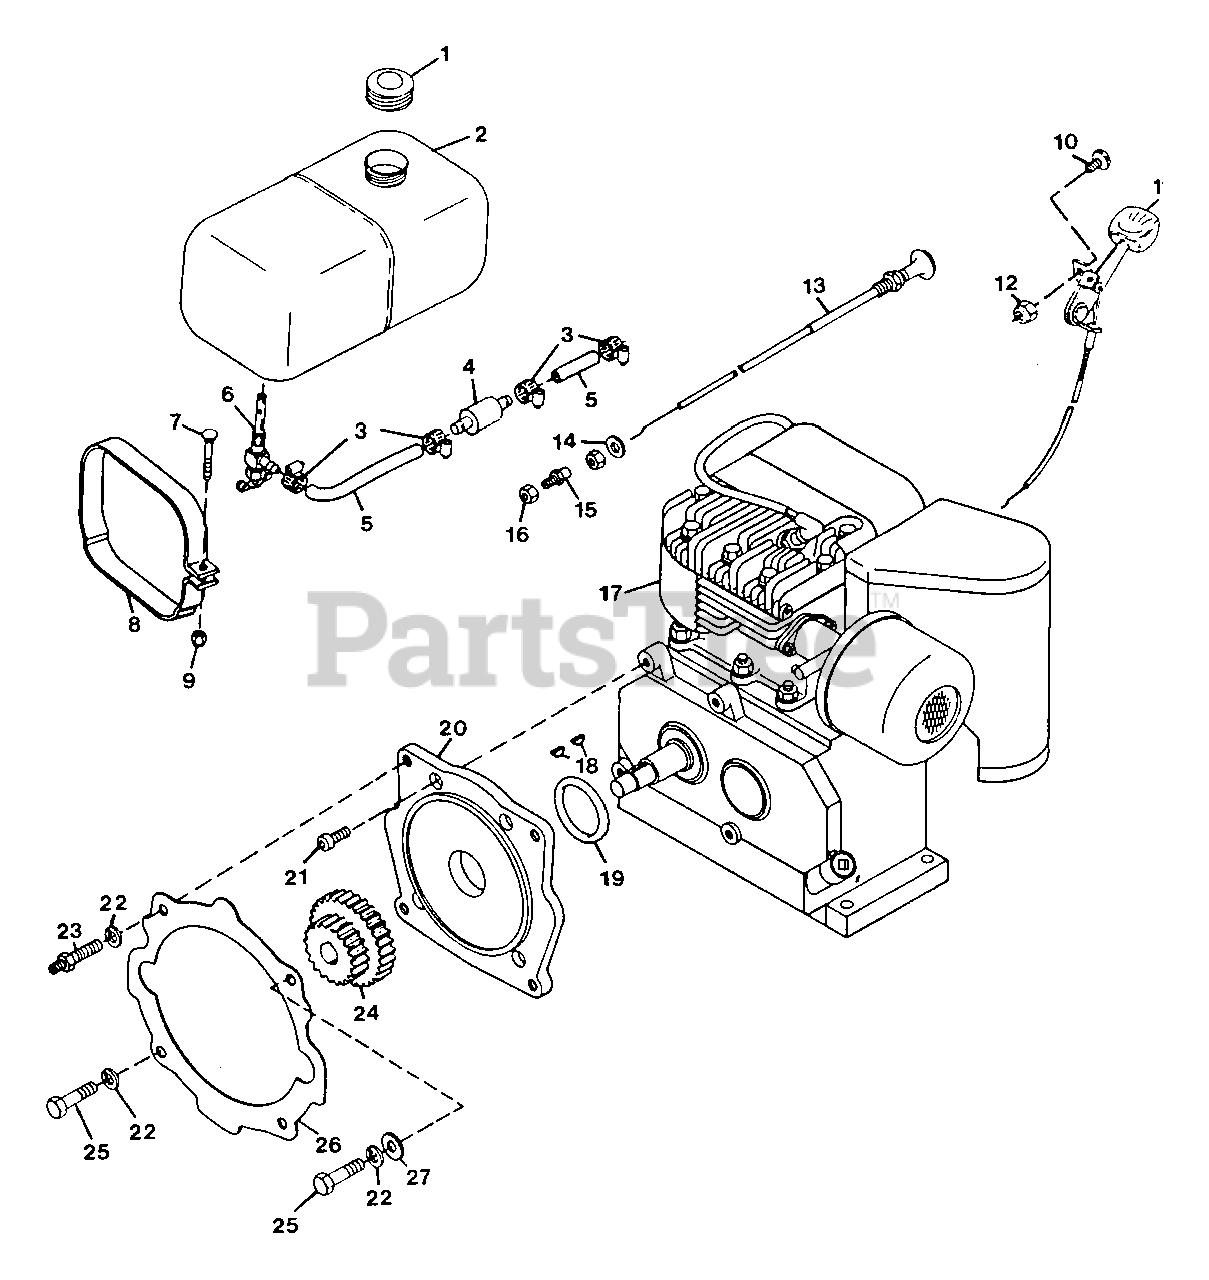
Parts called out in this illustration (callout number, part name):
1	Cap, Gas Tank
2	Assembly, Fuel Tank
3	Clamp, Hose
4	Filter, Fuel
5	Line, Fuel
6	Valve and Strainer
7	Bolt, 1/4-20x1.75 Rd.Hd.Sq.Nk.
8	Strap, Fuel Tank
9	Nut, Lock 1/4-20
10	Screw, Mach. 10-24x.50 PHD
11	Lever, Throttle
12	Nut, Lock 10-24
13	Lever, Choke Control
14	Washer, Flat .406x.812x.065
15	Adaptor, Conduit
16	Nut, Hex 1/4-20
17	Engine, 10 HP Manual
17	Engine, 10 HP Electric
18	Key, Woodruff 5/32x5/8 Hrd #6
19	O-Ring
20	Adaptor, Engine
21	Bolt, Hex M10-1.5X25 SKTHD
22	Washer, Lock 7/16 SP Heavy
23	Stud
24	Gear, 10/12 DP 21/30 Teeth
25	Bolt, Hex 7/16-14x1.25
26	Gasket, Chassis to Adaptor
27	Washer, Flat .469x.938x.065
